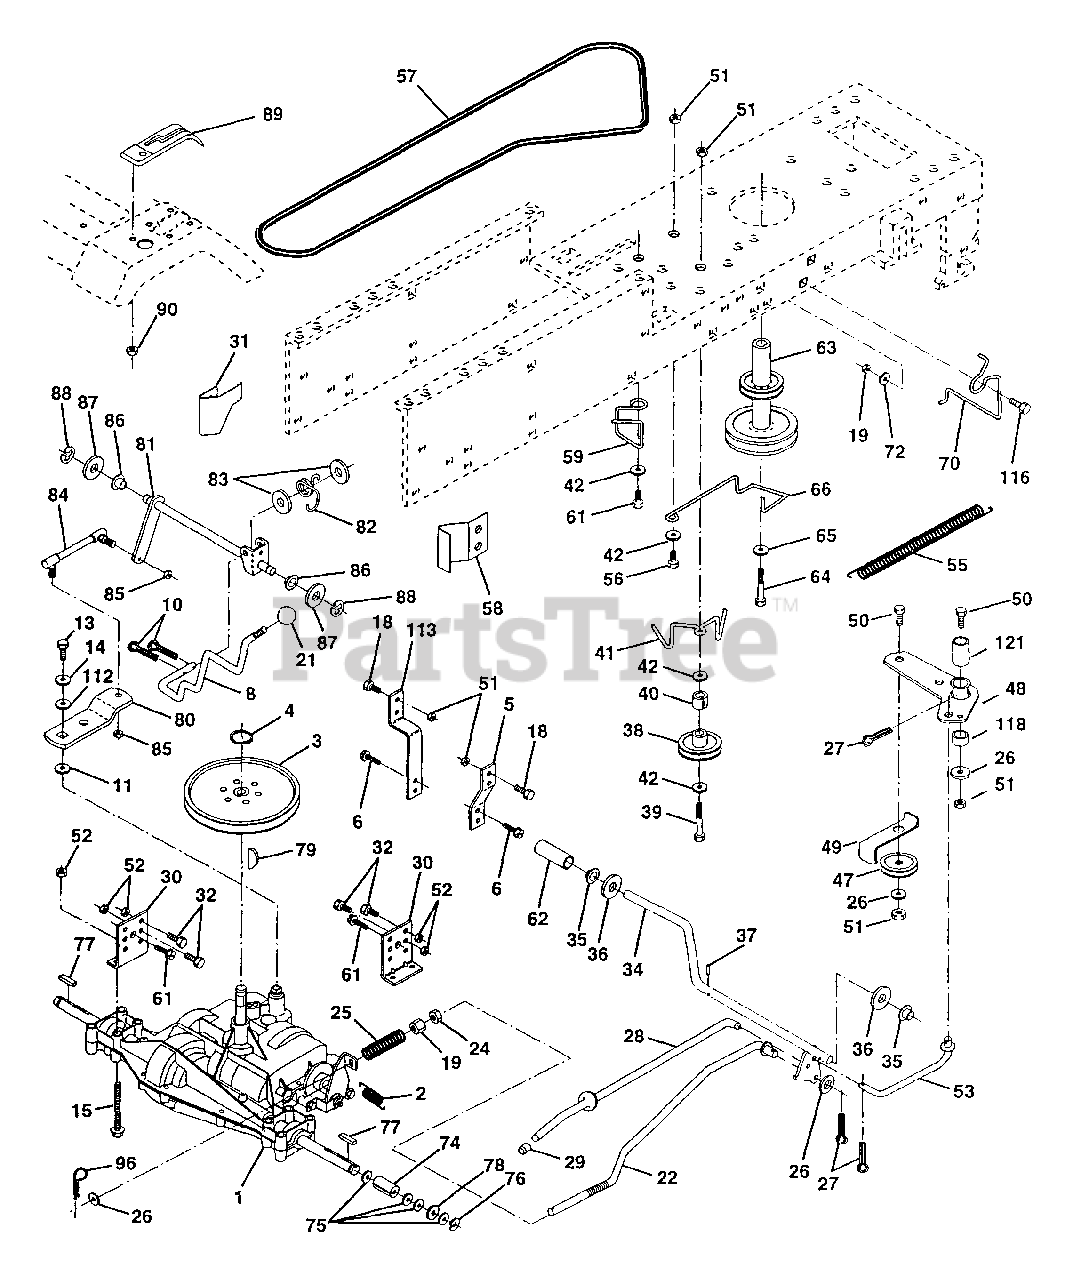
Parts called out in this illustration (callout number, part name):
1	Transaxle
2	Spring Return Brake T/a Zinc
3	Pulley Transaxle 18" tires
4	Ring Retainer # 5100-62 (AYP part number)
5	Strap Torque 30 Degrees
6	Screw Thdrol 5/16-18 X 3/4 TYT
8	Rod Shifter
10	Pin Cotter 1/8 X 1 Cad
11	Washer Plate Shf 388 Sq Hole
13	Bolt 1/4-28 Unf Gr 8 W/Patch
14	Washer Lock Hvy Helical 1/4
15	Bolt Hex 5/16-18 Gr. 5
18	Bolt, Fin Hex 3/8-16 UNC x 1 Gr. 5
19	Nut Lock 3/8-16 Unc
21	Knob
22	Rod Brake Blk Zinc 26 840
24	Nut Hex Jam 3/8-16 Unc
25	Spring Rod Brake 2 00 Zinc
26	Washer 13/32 X 13/16 X 16 Ga
27	Pin Cotter 1/8 X 3/4 Cad
28	Rod Brake Parking LT/YT
29	Cap Brake Parking
30	Bracket Mtg Transaxle
31	Keeper Belt LH LT 14 Ga
32	Bolt Hex Hd 5/16-18 unc X 3/4
34	Shaft Asm Pedal Foot
35	Bearing Nylon Blk 629 Id
36	Washer 21/32 X 1 X 16 Ga
37	Pin Roll 3/16 X 1" (AYP part number)
38	Pulley Idler Flat (AYP part number)
39	Bolt Fin Hex 3/8-16 unc X 2-3/4
40	Spacer Split 395 X 59 Bzp
41	Keeper Belt Retainer Idler Foolproof
42	Washer 13/32 X 13/16 X 12 Ga
47	Pulley Idler V Groove Plastic (AYP part number)
48	Bellcrank Asm
49	Retainer Belt Style Spring
50	Bolt Hex Hd 3/8-16 unc X 1-1/2 (AYP part number)
51	Nut Crownlock 3/8-16 Unc
52	Nut Crownlock 5/16-18 Unc
53	Link Clutch
55	X Spring Return Clutch 6 75 (AYP part number)
56	Bolt Fin Hx 3/8-16 X 1/4
57	V-Belt Ground Drive 95 25
58	Keeper Belt RH LT Pnt/zinc 16g
59	Keeper Belt Span Ctr (AYP part number)
61	Screw Thdrol 3/8-16 x 3/4 Ty-tt
62	Cover Pedal Blk Round
63	Engine Pulley LT/YT
64	Bolt Hex (AYP part number)
65	Washer Lock Hvy Hlcl Spr 7/16
66	Keeper Belt Engine Foolproof
70	Guide Belt Mower Drive RH
72	Washer 13/32 X 1-1/4 X 12 Ga
74	Spacer Axle
75	Washer 25/32 X 1 1/4 X 16 Ga
76	E-ring #5133-75
77	Key Square 2 0 X 1845/1865
78	Washer 25/32 X 1-5/8 X 16 Ga
79	Key Woodruff #9 3/16 x 3/4 (AYP part number)
80	Arm Shift
81	Shaft Asm Cross 18"t
82	Spring Torsion T/a
83	Washer 17/32 X 3/4 X 16 Ga
84	Rod Shift
85	Nut Lock Center 1/4-28 FNTHD
86	Bushing Rod Strg 629/632 Id
87	Washer 21/32 X 1-1/4 X 16 Ga
88	Ring Klip #5304-62
89	Console Shift STLT (AYP part number)
90	Nut Self-thd Wsh-hd 1/4 Zinc
96	Retainer Spring 1"
112	Washer 9/32 x 3/4 x 10 Ga.
113	Strap Torque LT
116	Bolt Rdhd Sq Neck 3/8-16 x 1.25 (AYP part number)
118	Spacer Bellcrank
121	Nyliner Clutching STL
